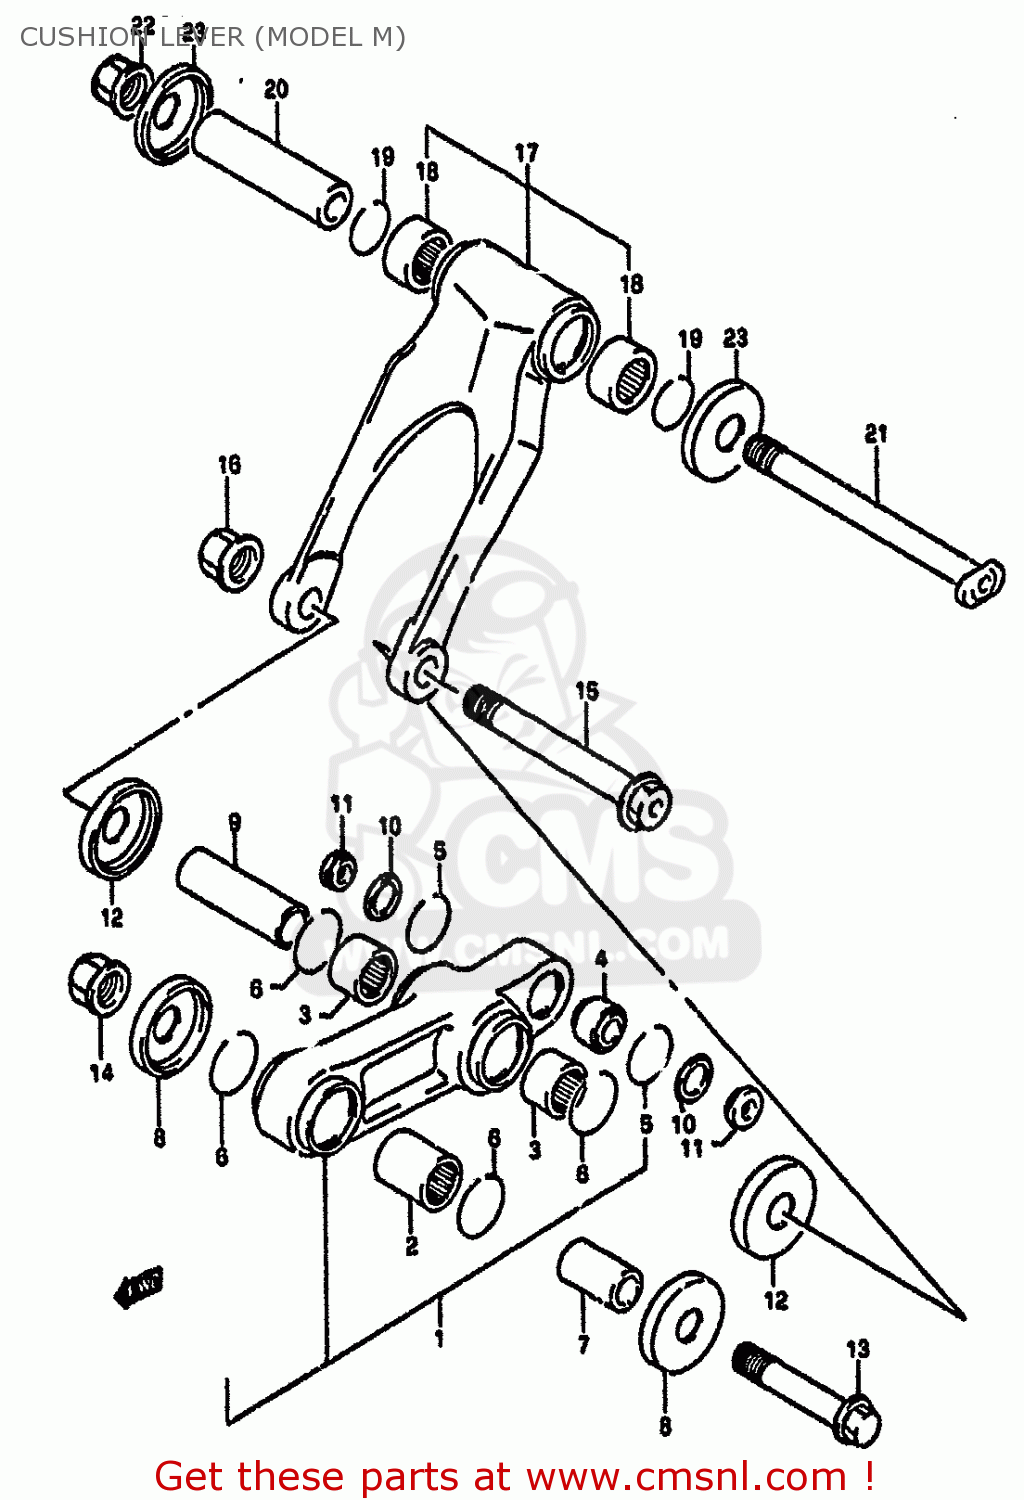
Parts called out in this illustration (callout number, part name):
1	LEVER SET,REAR CUSHION
2	BEARING(20X27X25)
3	BEARING(21X27X20)
4	BEARING,RR CUSHION LEVER
5	RING
6	CIRCLIP
7	SPACER,RR CUSHION LEVER FR
8	SEAL,REAR CUSHION LEVER
9	SPACER,REAR CUSHION LEVER,C
10	SEAL,RR CUSHION LEVER RR DUST
11	SPACER,RR CUSHION LEVER RR
12	SEAL,REAR CUSHION LEVER
13	BOLT,RR CUSHION LEVER FR
14	NUT 12MM
15	BOLT,REAR CUSHION LEVER,CENTER
16	NUT
17	LEVER SET,REAR CUSHION
18	BEARING(21X27X20)
19	CIRCLIP
20	SPACER,RR CUSHION ROD
21	BOLT,RR CUSHION ROD
22	NUT
23	NUT
24	SEAL,RR CUSHION LEVER
